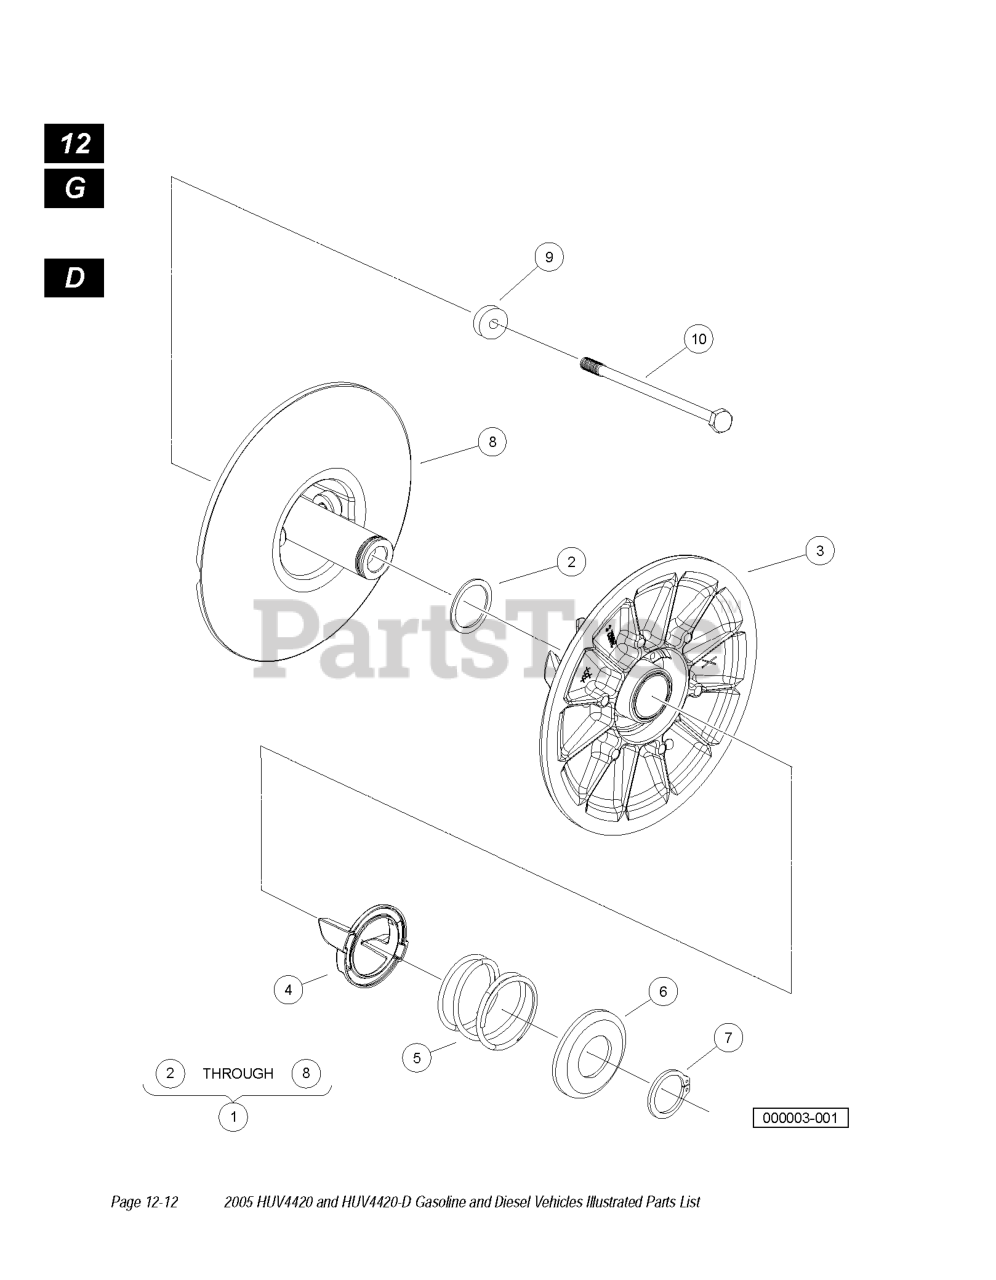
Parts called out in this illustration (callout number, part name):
1	CVT, SECONDARY
2	WASHER, THRUST, 1.53 X 1.92
4	RETAINER, SPRING, INNER
5	SPRING, COMPRESSION, SECONDARY
6	RETAINER, SPRING, OUTER
7	RING, RETAINING, EXTERNAL
9	WASHER, STEPPED, CVT SECONDARY
10	BOLT, M10 X 1.5 X 100 LOCTITE
